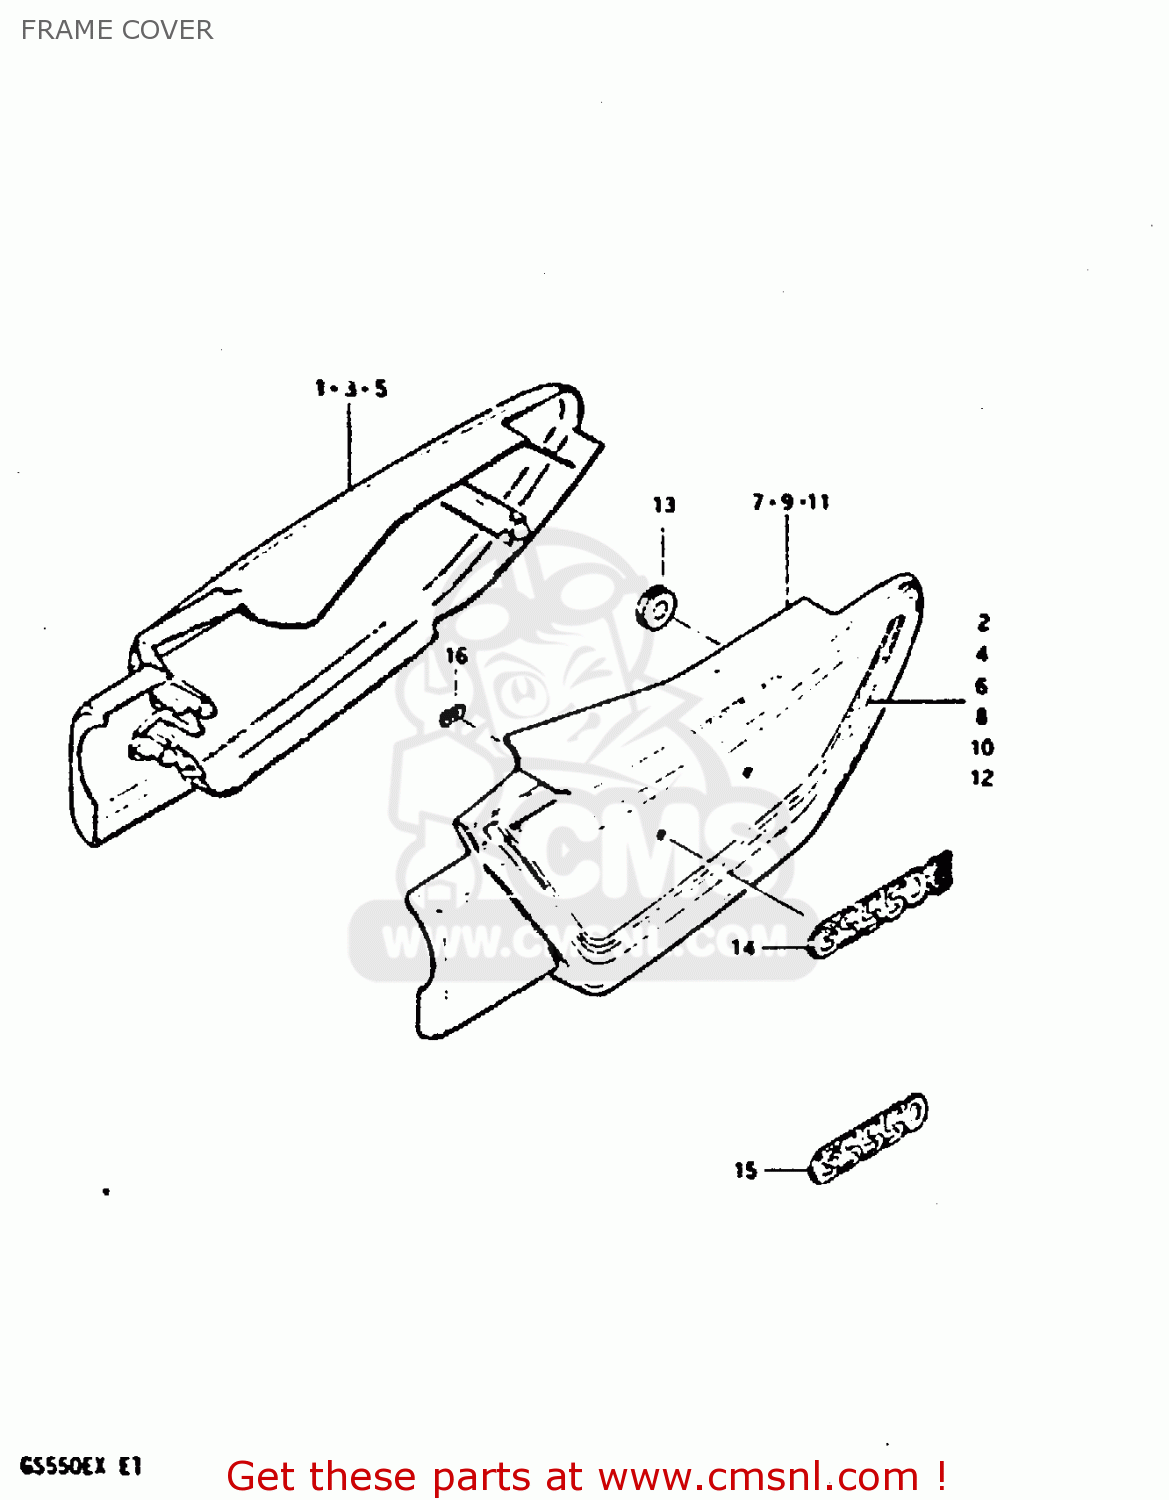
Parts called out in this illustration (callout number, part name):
1	COVER,FRAME,RIGHT
2	TAPE, RH
3	COVER, FRAME RH (RED)
4	TAPE, RH
5	COVER, FRAME RH (BLUE)
6	TAPE, RH
7	COVER,FRAME,LEFT
8	TAPE, LH
9	COVER, FRAME LH (RED)
10	TAPE, LH
11	COVER, FRAME LH (BLUE)
12	TAPE, LH
13	CUSHION
14	EMBLEM
15	EMBLEM
16	NUT
